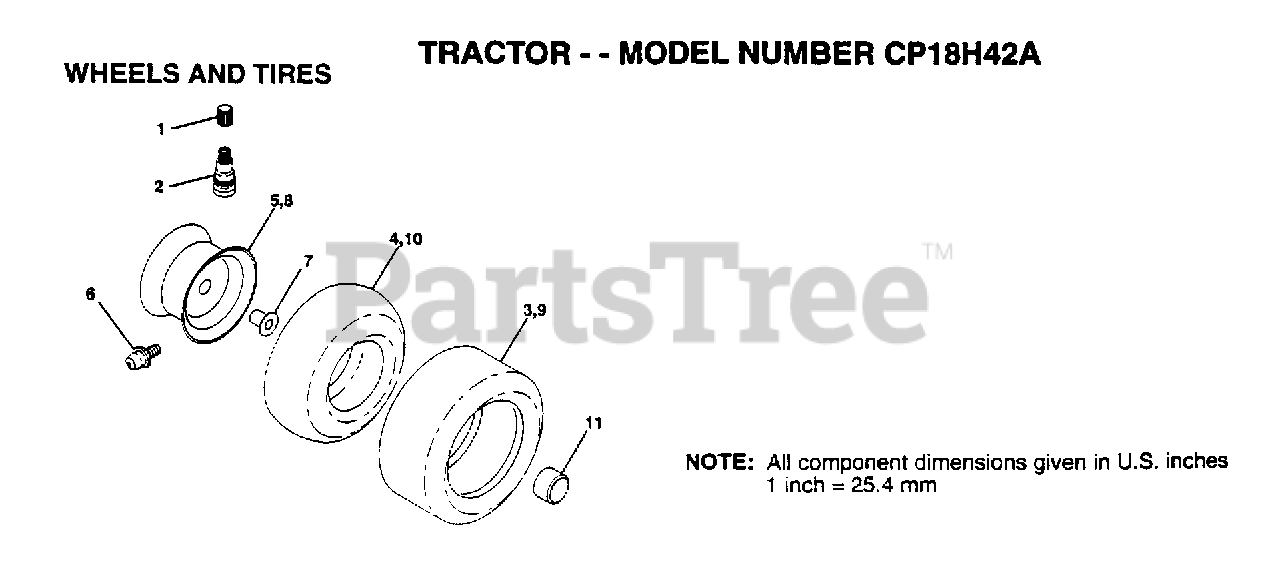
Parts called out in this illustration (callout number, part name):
1	VALVE CAP
2	VALVE STEM LT
4	TUBE.5.3/4.5/6
5	"RIM,FRT T"
6	FITTING LT
7	"FLANGE, BEARING"
8	"RIM 8"""
9	TIRE.20X8-8
10	TUBE.18X9.5-8
11	HUB CAP
